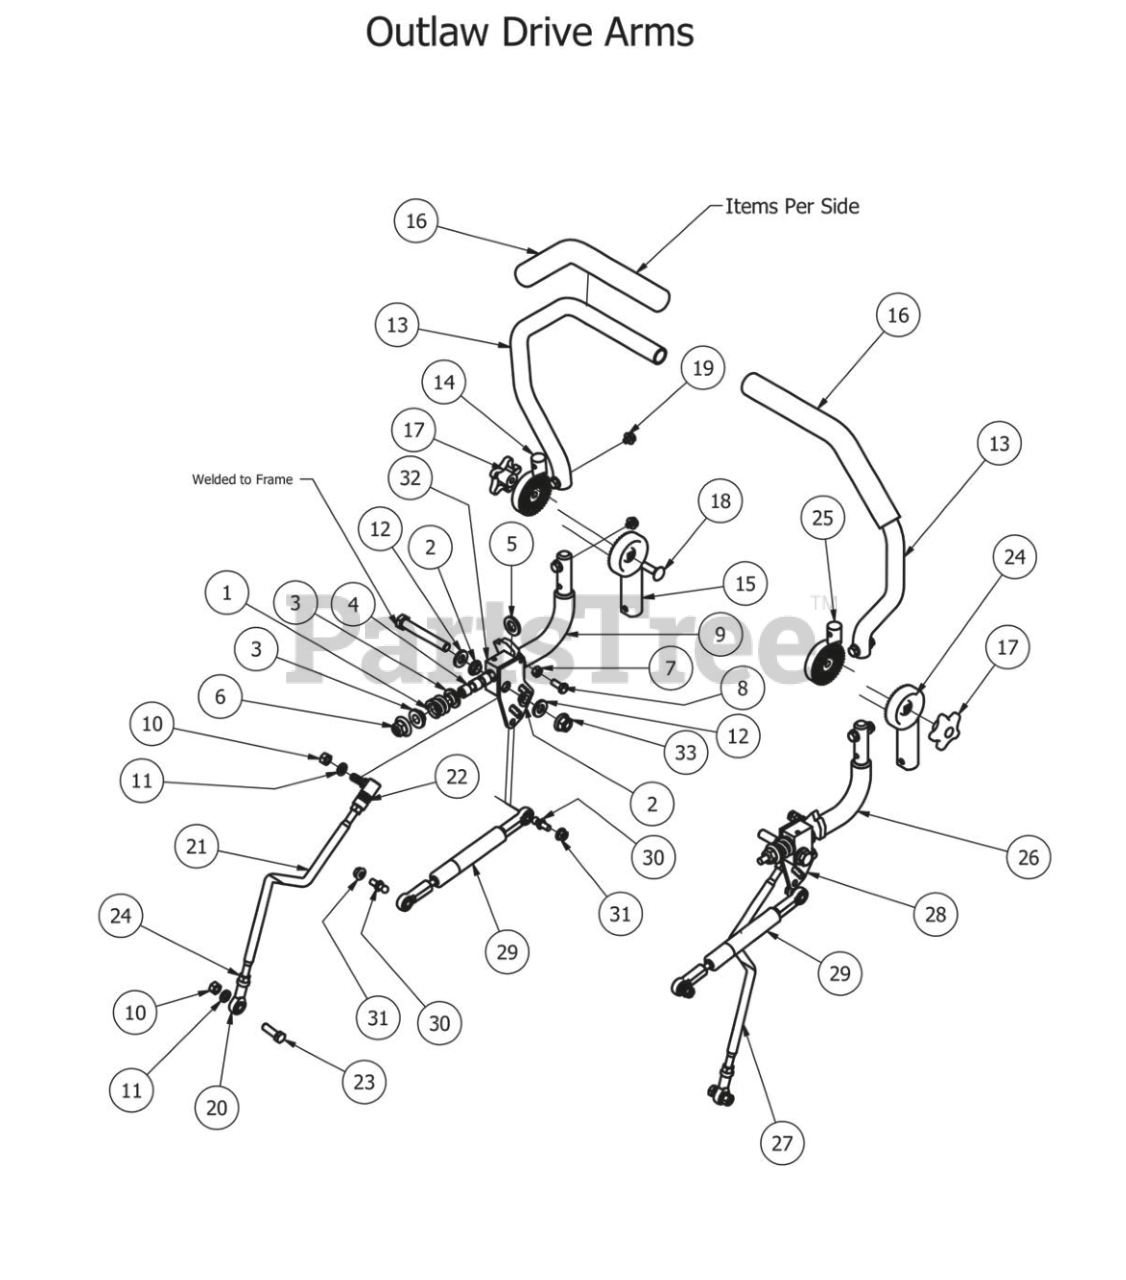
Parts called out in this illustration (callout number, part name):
1	Drive Lever Spring
2	Bushing for 2012 Drive Arms
3	.515 ID Nylon Shoulder Washer
4	.507 ID Nylon Bushing
5	.635 ID Plastic Washer
6	1/2-13 Nylon Flange Nut-Orange
8	5/16" x 3/4" Hex Bolt
9	Steering Arm Elbow - Left
10	3/8" Fine Threaded Jam Nut
11	3/8" Lock Washer
12	.505x1x.125 Oil Impregnated washer
13	Upper Tube-Adjustable Steering
14	Upper adjuster-Steering Arm- Left
15	Lower Adjuster - Steering Arm- Left
16	Black Steering Grip
17	Black Knob for Adjustable Steering Arm
18	3/8" x 1 1/4" Carriage Bolt
19	5/16-18 1/2 HWH Bolt-Steering
20	Spherical Rod End - Outlaw
21	Push Rod for Outlaw - Left
22	Quick Release Ball Joint
23	3/8" x 1 1/4" Hex Bolt
24	Lower Adjuster - Steering Arm- Right
25	Upper Adjust Steering Arm- Right
26	Steering Arm Elbow - Right
27	Push Rod for Outlaw - Right
28	2013 Drive Lever Housing (Right)
29	Steering Damper For Outlaw
30	10mm Damper Ball Stud-Steering
31	5/16" Flange Nut
32	2013 Drive Lever Housing (Left)
33	1/2-13 Hex Flange (GR.G) ZC
